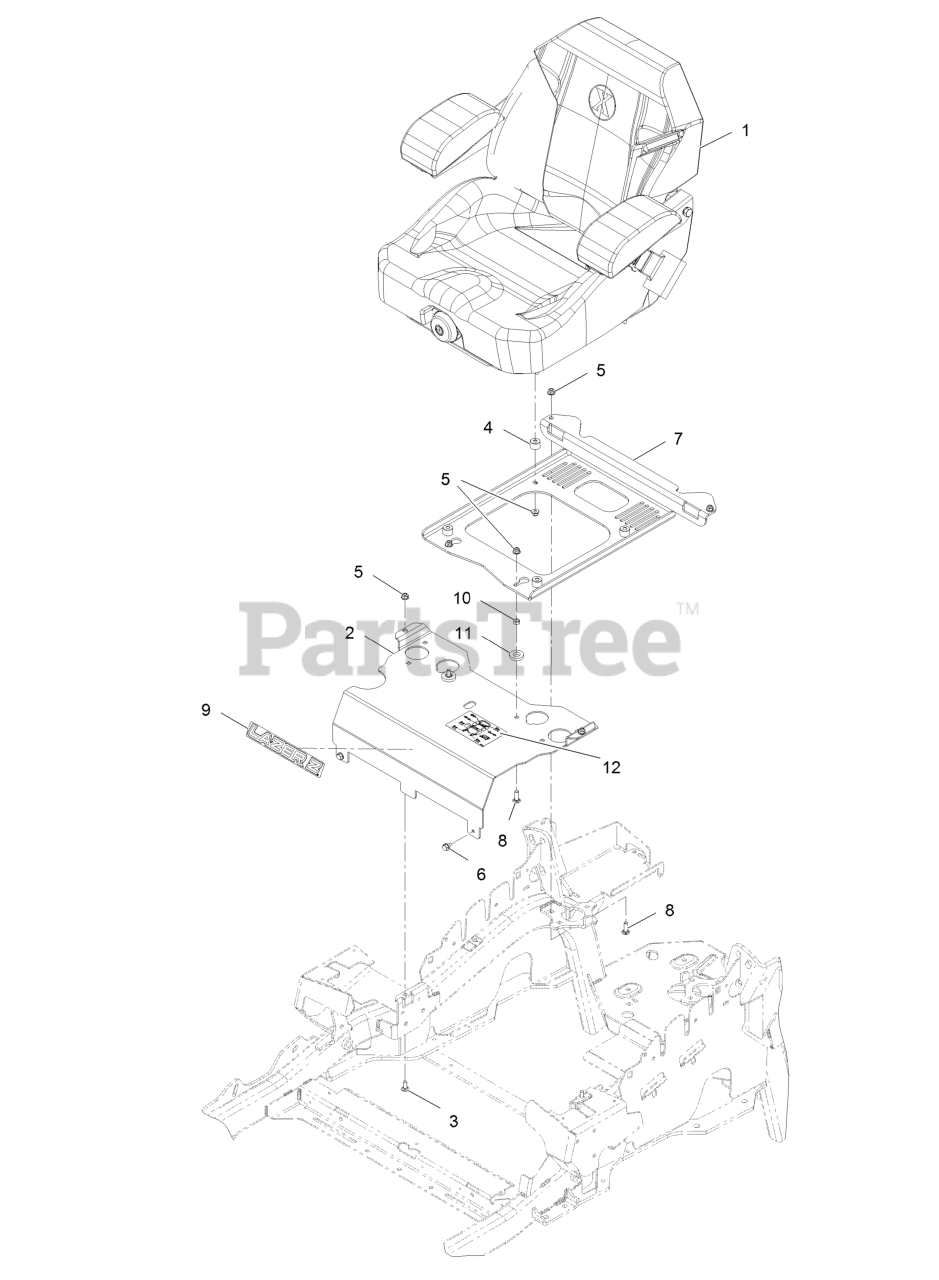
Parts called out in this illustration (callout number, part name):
1	Kit-Suspension Seat
2	Panel-Front, Seat Mount
3	Bolt-Carriage 5/16-18 X 3/4 Short Neck
5	Nut-Nyloc 5/16-18 Flg
6	Screw-HWH 5/16 X 1/2 Tf
7	Plate-Support, Seat
8	Bolt-Carriage 5/16-18 X 1 Sp
9	Decal, Lazer Model
10	Nut-Hex 5/16-18
11	Spacer-Blade Drive
12	Decal-Service Aid
